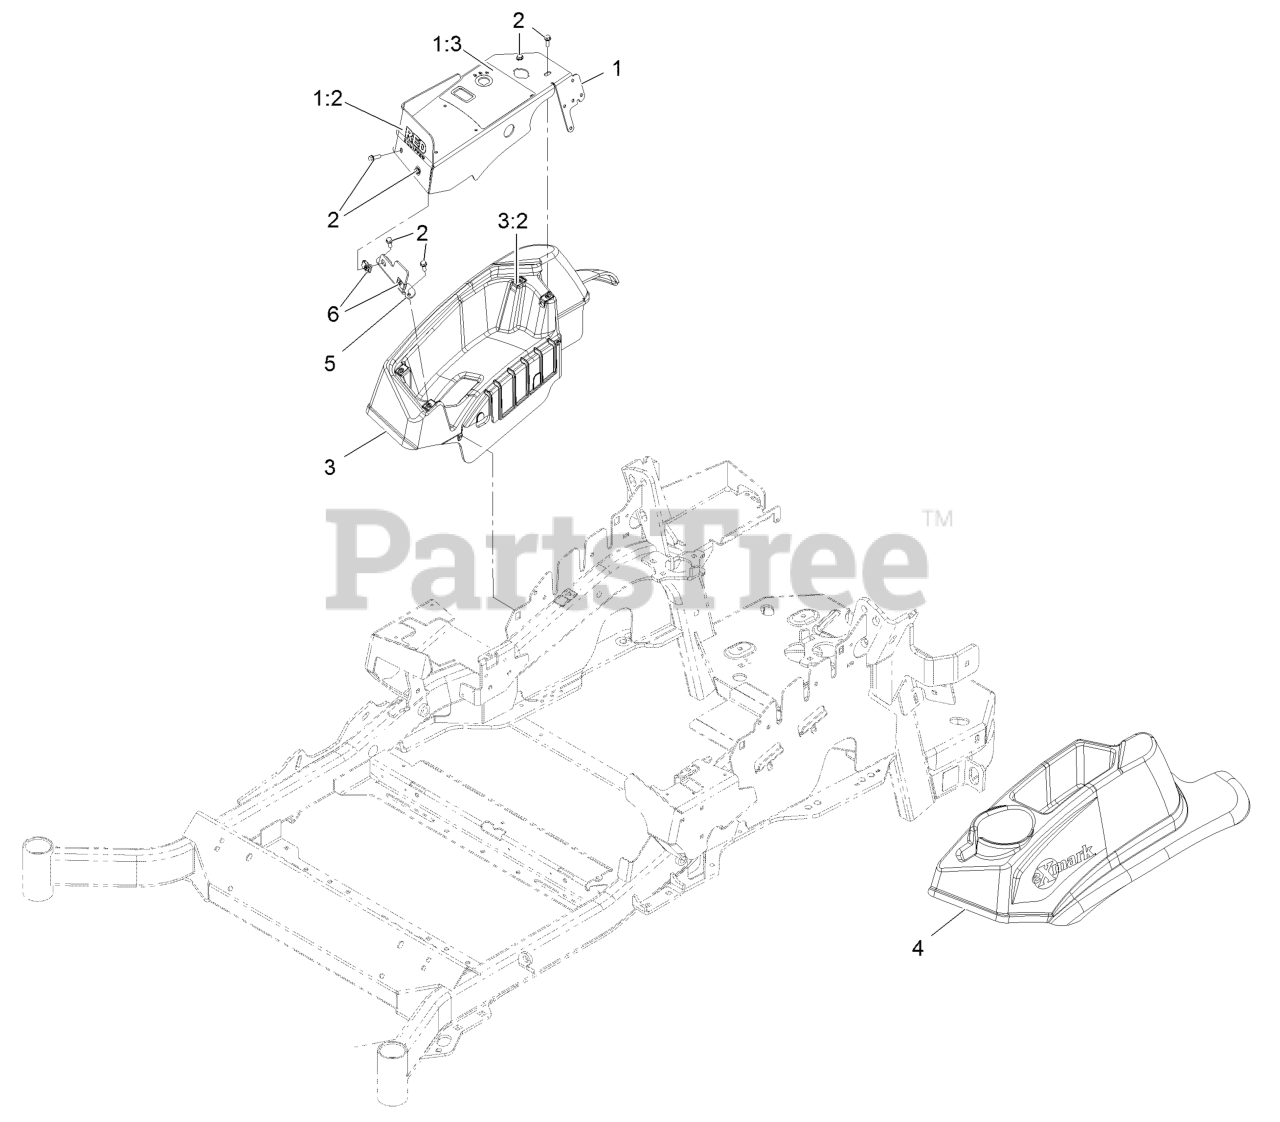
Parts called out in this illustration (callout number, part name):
1	Cover Panel ASM W/Decals
1:2	Decal-Control Panel Red
1:3	Decal-Console
2	Screw-Machine 1/4-20 X 3/4
3	Console,RH As ASM
3:2	Nut-Retainer-Panel 1/4-20
4	Console, LH As
5	Bracket-Console
6	Nut-Retainer-Panel 1/4-20
